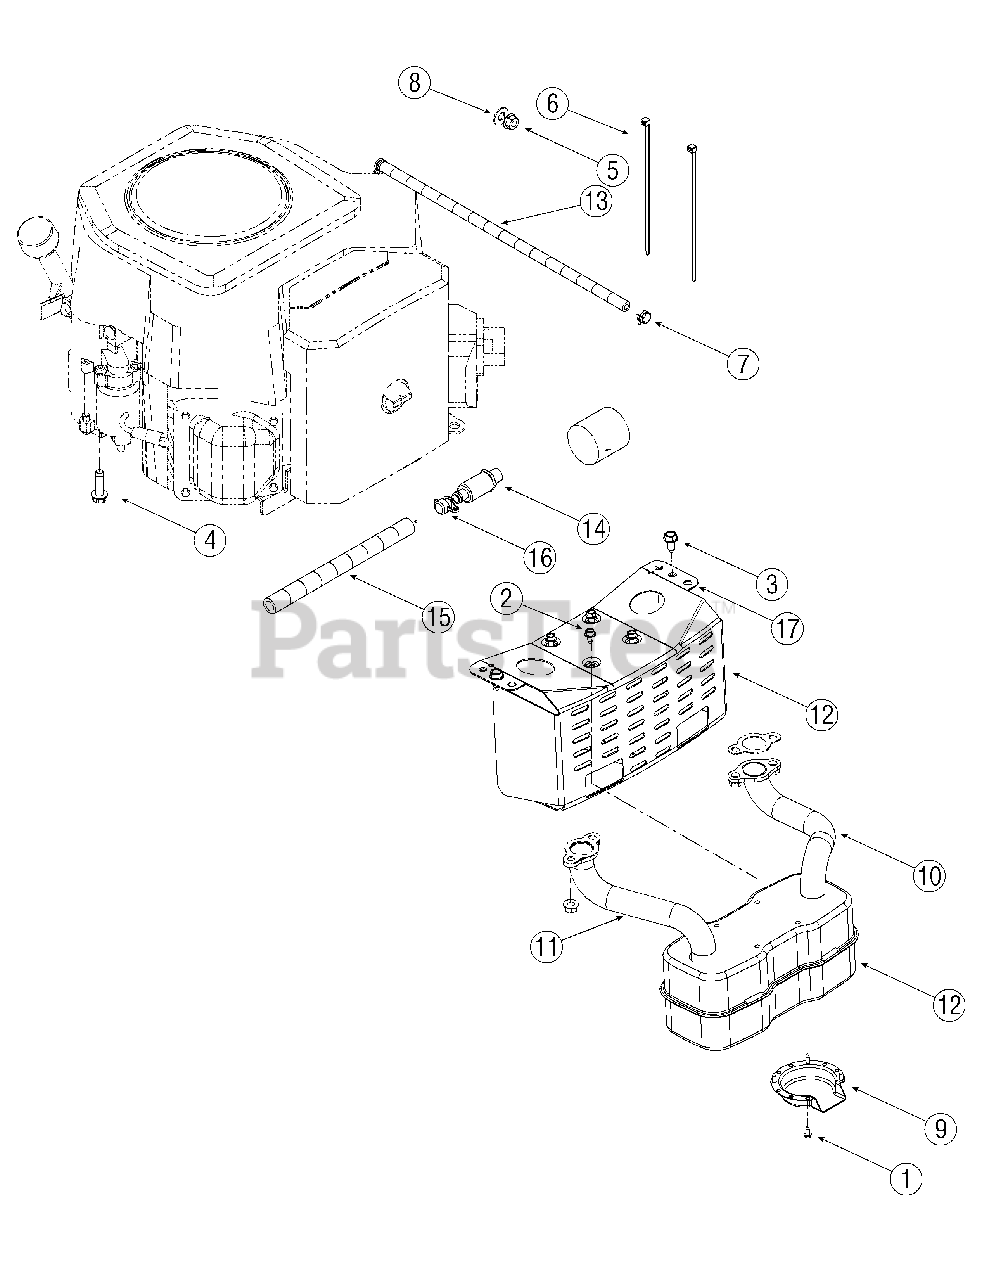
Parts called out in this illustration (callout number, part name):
1	Self-tapping Screw, #8-18 x.50
2	Self-tapping Screw, 1/4-20 x.50
3	Self-tapping Screw, 5/16-18 x.625
4	Self-tapping Screw, 3/8-16 x 1.25
5	Flange Lock Nut, 3/8-16
8	Lock Washer,.406 x.875 x.059
9	Muffler Deflector
10	LH Exhaust Pipe (Kohler V-Twin)
11	RH Exhaust Pipe (Kohler V-Twin)
12	Muffler, Twin Inlet (Kohler V-Twin)
13	Fuel Line Hose
14	Oil Drain Valve
15	Oil Drain Hose
16	Oil Drain Cap
